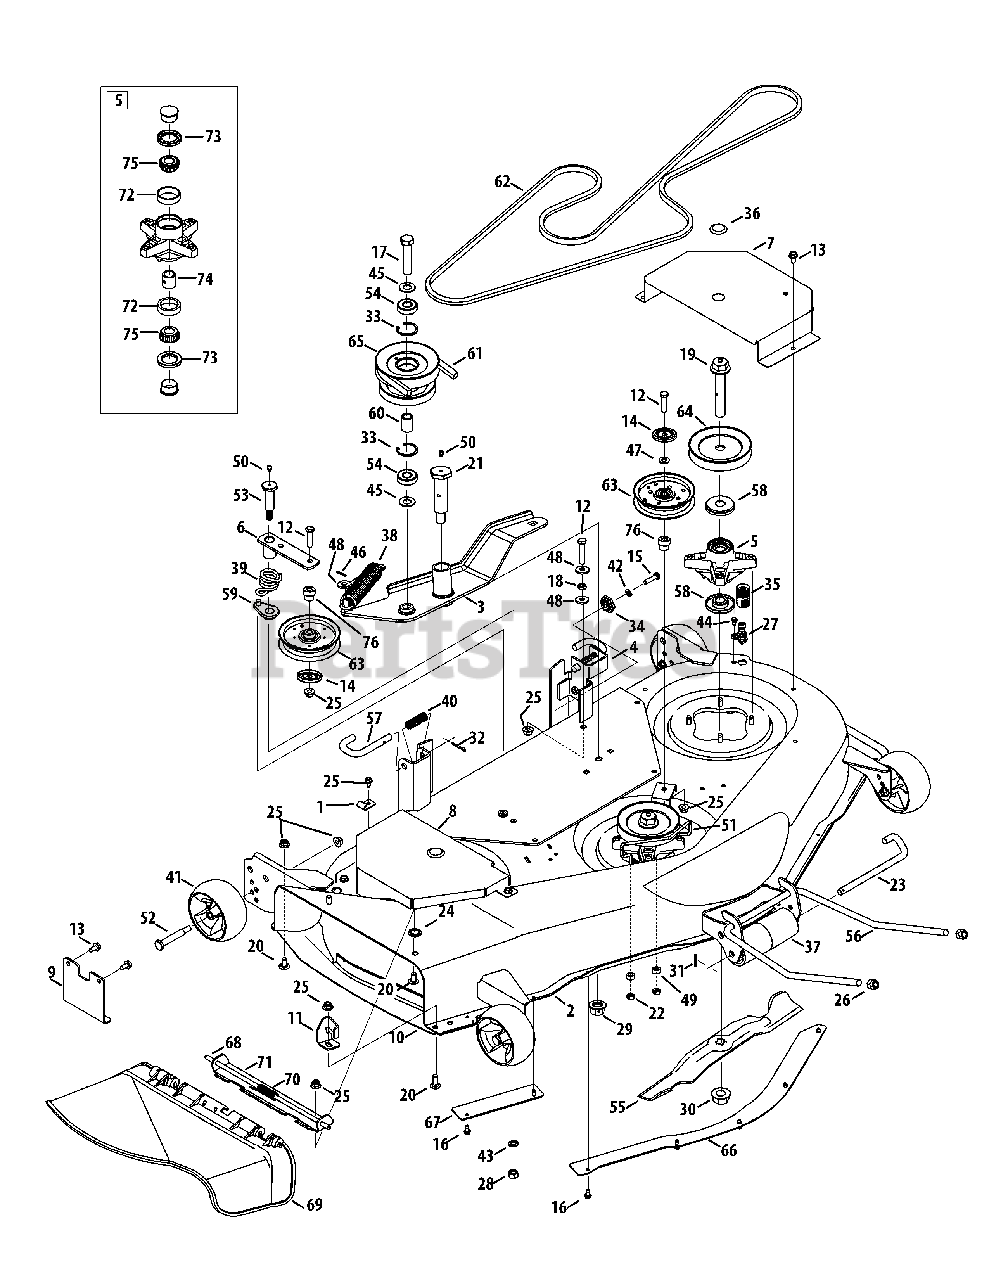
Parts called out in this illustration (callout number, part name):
1	Hook Retainer Bracket
4	Hanger Adjustment Bracket
5	Spindle Assembly
7	LH Spindle Shield
8	RH Spindle Shield
9	Up-Stop Bracket
12	Hex Screw, 3/8 x 16 x 1.75
13	Hex Washer Screw, 5/16-18 x .750
14	Pulley Cap
15	Hex Screw, 5/16-18 x 1.25
16	Hex Washer Screw, 1/4-20 x .500
17	Hex Screw, 5/8-18 x 3.00
18	Jam Nut, 3/8 x 16
19	Spindle Bolt, 3/4-16 x 4.25
20	Carriage Bolt, 3/8-16 x 1.00
21	Shoulder Screw, 1.0 x 3.00
22	Hex Lock Nut, 1/4-20
23	Roller Pin, 1/2 x 7.31
24	Push Nut, 3/8
25	Flange Lock Nut, 3/8-16
26	Hex Nut, 1/2-13
27	Deck Wash Nozzle
28	Hex Nut, 7/16-14
29	Flange Lock Nut, 5/8-18
30	Flange Lock Nut, 3/4-16
31	Cotter Pin, 3/32 x 1.25
32	Cotter Pin, 5/32 x 1.25
33	Retainer Ring
34	Deck Adjustment Gear
35	Water Nozzle Adapter
36	Button Plug
37	Front Roller
38	Extension Spring, 1.25 x 6.9
39	Idler Torsion Spring, 1.10 x 1.3
40	Compression Spring, .66 x 1.8
41	Deck Wheel, 5.0
42	Lock Washer, 5/16
43	Lock Washer, 7/16
44	Shoulder Screw, 1/4-20 x 0.50
45	Flat Washer, .65 x 1.25 x .075
46	Cotter Pin, 3/32 x .750
47	Flat Washer, .406 x .812 x .051
48	Falt Washer, .385 x 1.00 x .135
49	Spacer, .256 x .500 x .240
50	Drive Lube Fitting, 3/16
51	Belt Drive Guard
52	Shoulder Screw, 1/2 x 2.50
53	Shoulder Screw, 7/16-14 x .687 x 2.443
54	Ball Bearing, .625 x 40 x 12
55	2-in1 Blade
56	Front Lift Rod
57	Mower Support Pin
58	Spindle Spacer
59	Spring Retainer
60	Spacer, .88 x .635 x 1.25
62	Deck Belt
63	Idler Pulley
64	Spindle Pulley
65	Double Pulley
68	Hinge Pin, .3175 x 14.06
69	Chute Deflector
70	Torsion Spring, .44 x 2.0
71	Chute Bracket
72	Bearing Cup, .750
74	Bearing Spacer, .78 x 1.0 x 1.0425
75	Cone Bearing, .750
76	Shoulder Spacer, Idler
